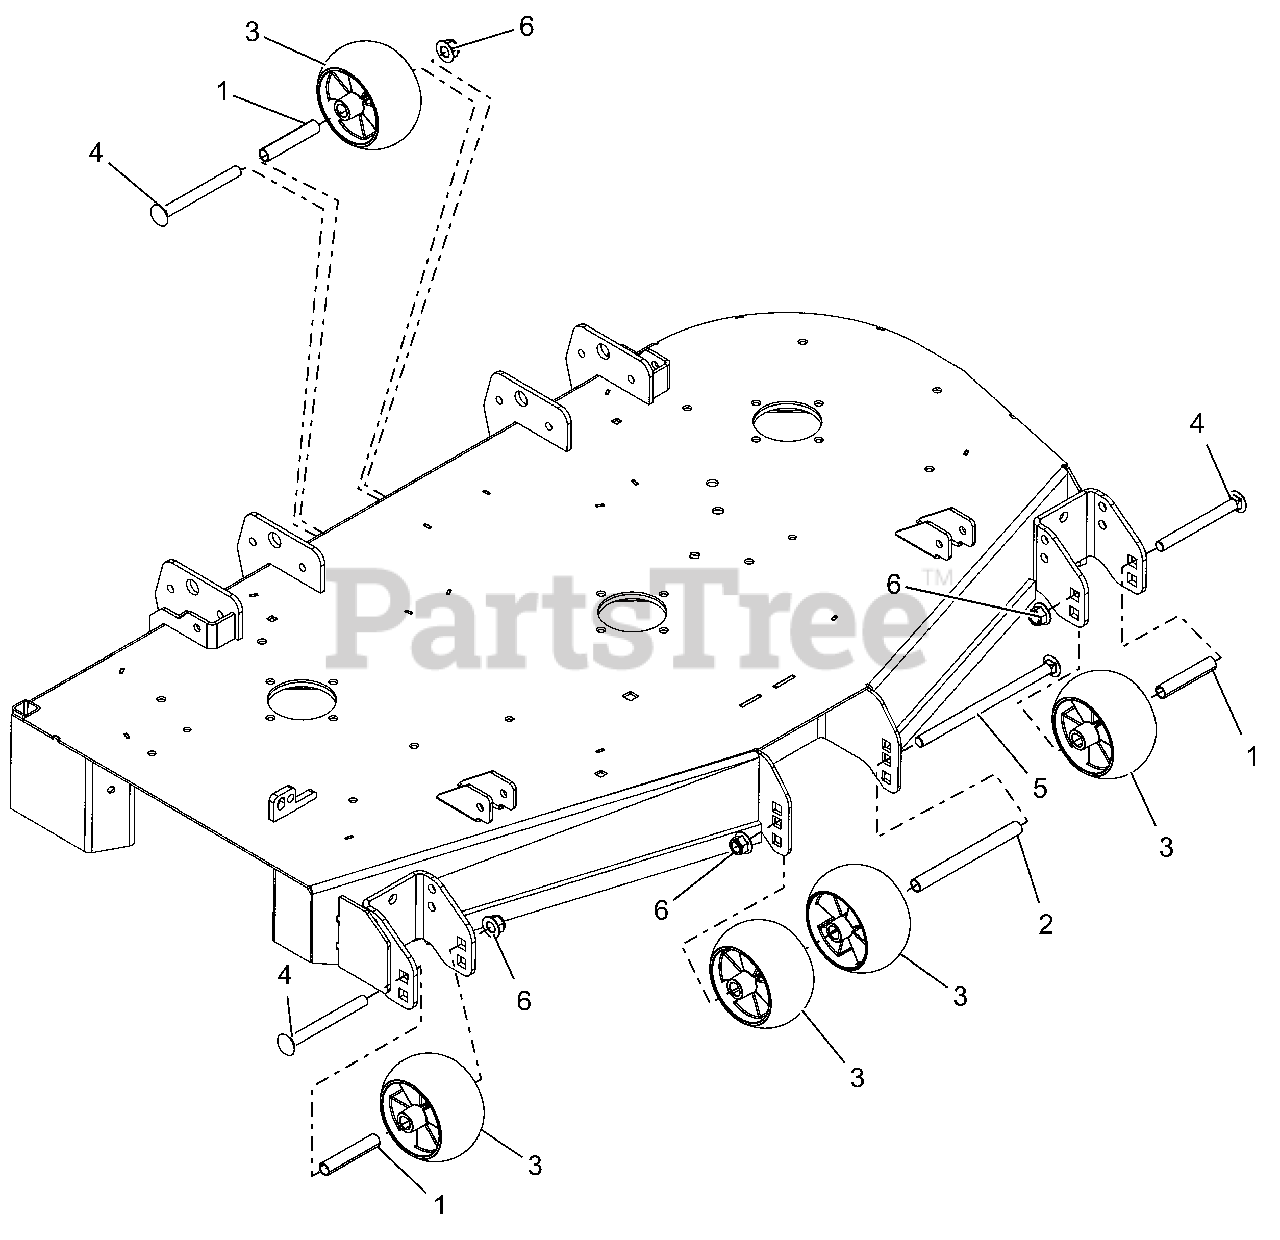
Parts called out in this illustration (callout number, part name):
1	.510X.625X3.35 SPACER-LOW FILM
2	.510X.625X6.50 SPACER-LOW FILM
3	ANTI-SCALP WHEEL - 5X3 CTR
4	BLT-RDHDSQNK .50-13X5.00 GR5YZ
5	@BLT-RDHDSQNK .50-13X8.50 G5YZ
6	@NUT-LK-NYL-FLG .50-13 YWZC
